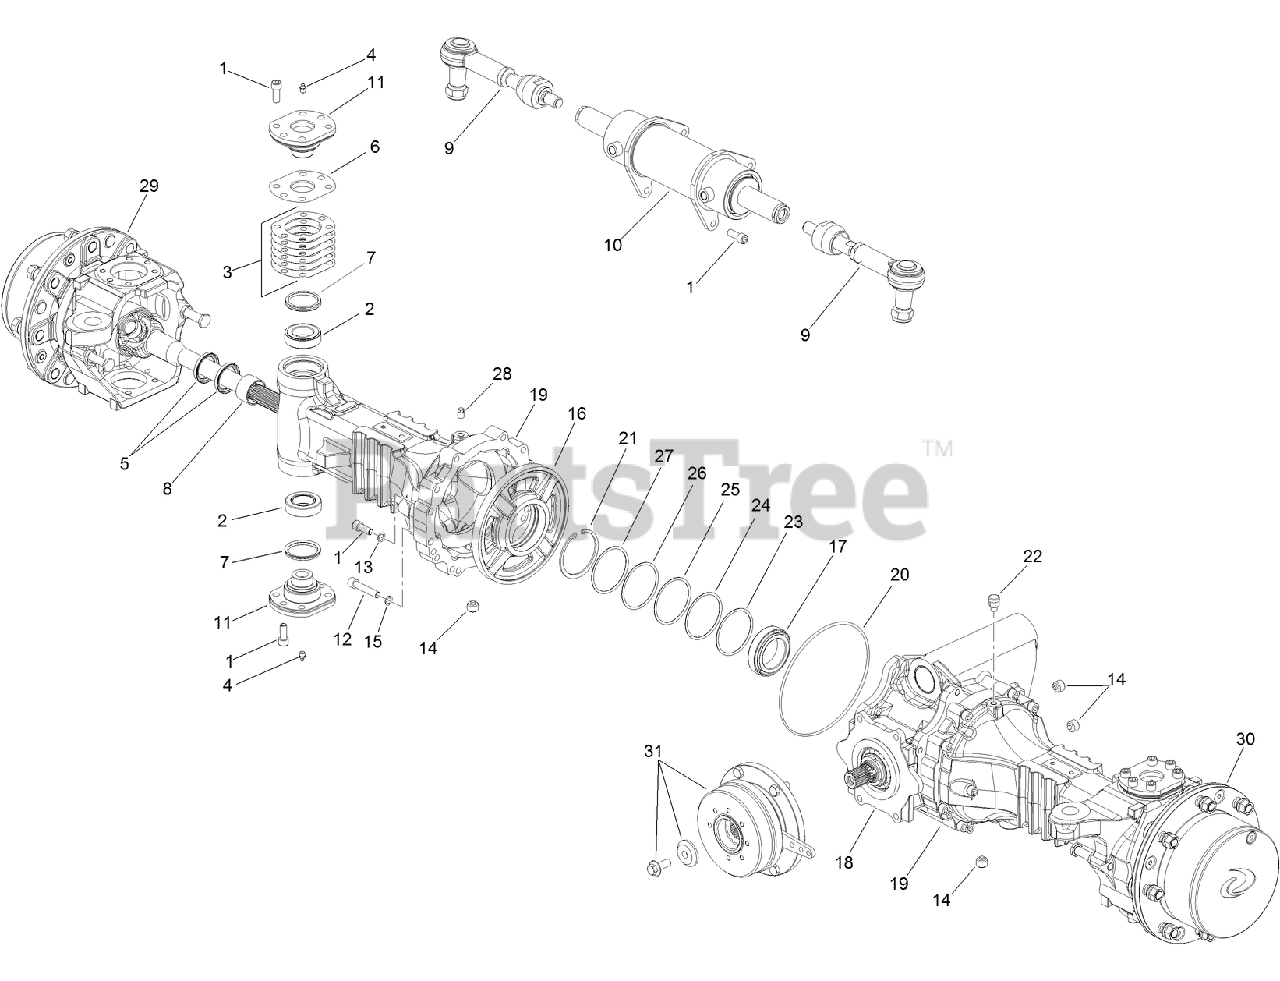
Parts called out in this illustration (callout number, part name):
1	SCREW-SOC HD
2	JOINT-BALL
3	SHIM-JOINT, ARTICULATED (0.2)
4	GREASER
5	SEAL-OIL
6	SHIM-JOINT, ARTICULATED (0.1)
7	V-RING
8	BUSHING
9	ROD-TIE
10	CYLINDER-STEERING
11	PIN-FLANGED
13	WASHER-COPPER
14	PLUG-MAGNETIC
15	WASHER-SCHNORR
16	FLANGE-DIFFERENTIAL
17	BEARING
18	PINION GROUP
19	HOUSING-SIDE
20	O-RING
21	RING-SNAP
22	PLUG-BREATHER
23	SHIM (1.0)
24	SHIM (0.2)
25	SHIM (0.3)
26	SHIM (0.35)
27	SHIM (0.5)
29	WHEEL HUB GROUP
30	WHEEL HUB GROUP
31	BRAKE GROUP
